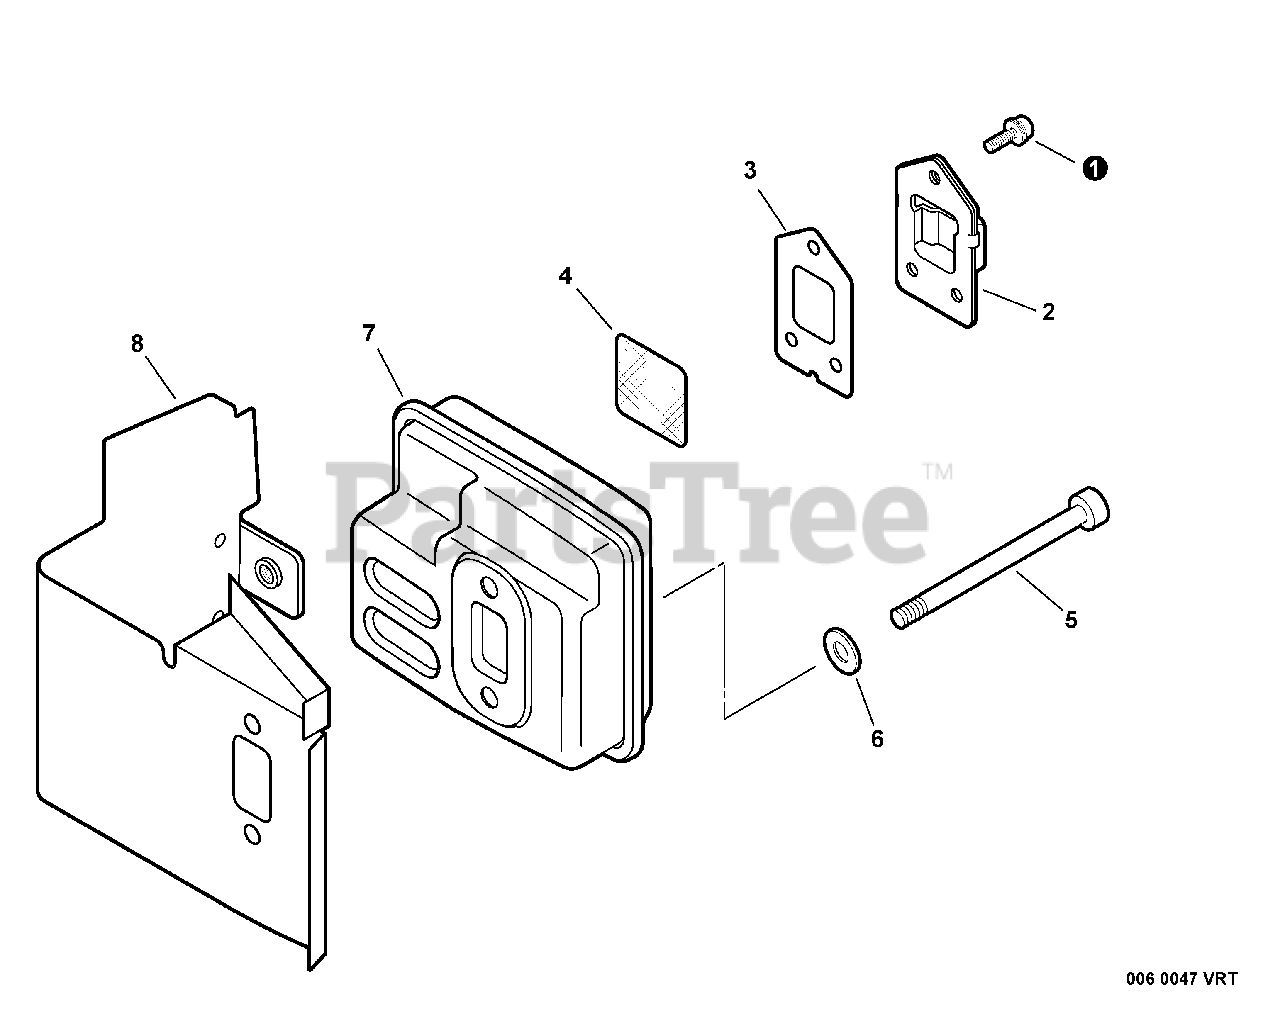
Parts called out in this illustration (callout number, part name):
1	SCREW - 4X10
2	GUIDE, EXHAUST
3	GASKET, EXHAUST
4	SCREEN, SPARK ARRESTOR
5	SCREW - 5X50
6	WASHER - 5
8	SHIELD, EXHAUST
